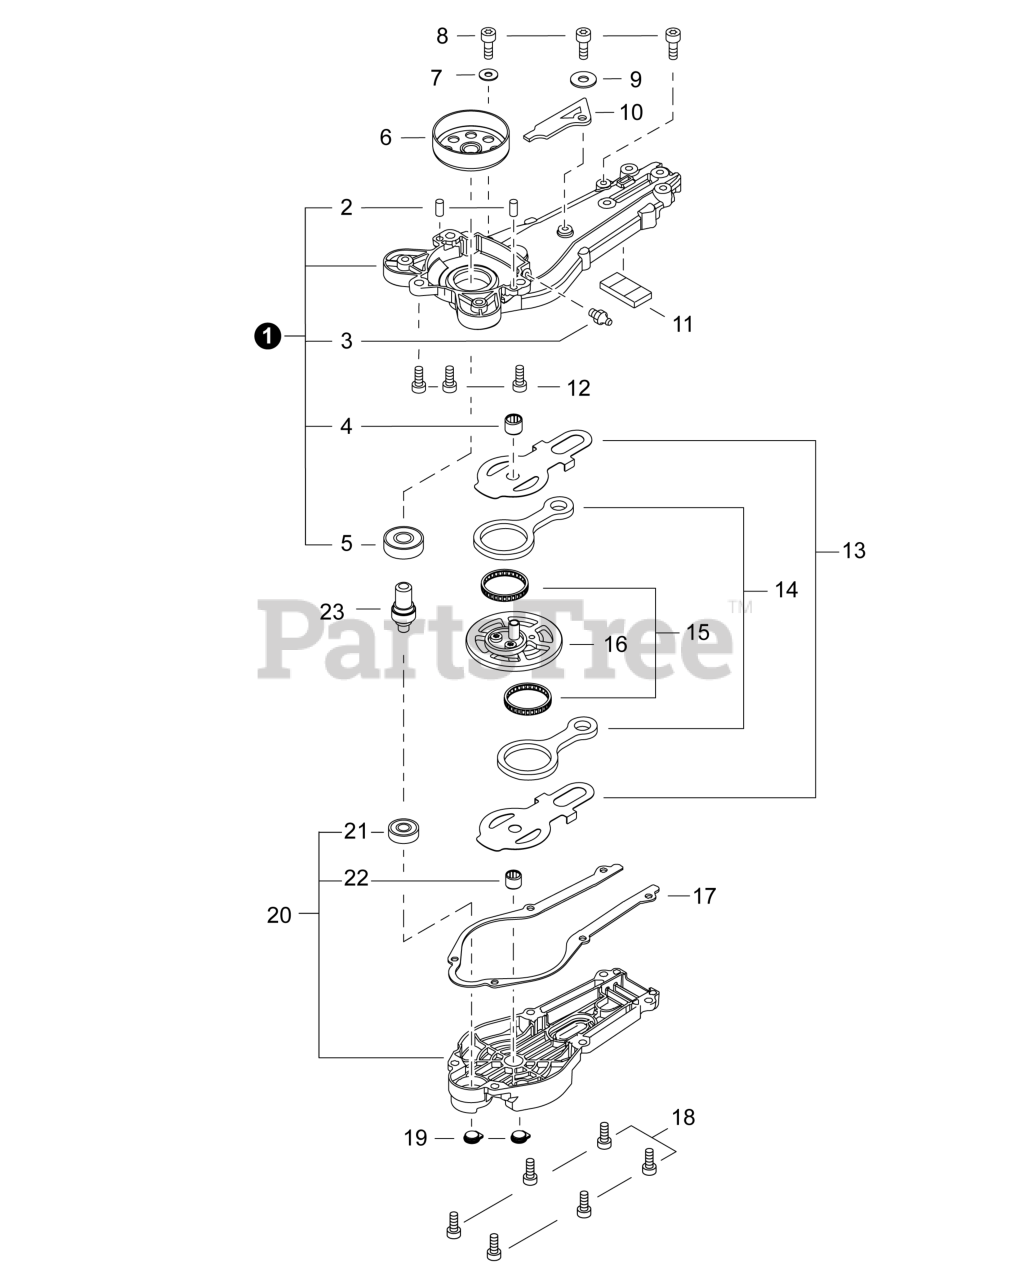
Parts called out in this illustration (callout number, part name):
1	HOUSING ASSY, GEAR CASE
2	PIN, LOCATING 4x8
3	FITTING, GREASE
4	BEARING, NEEDLE 8
5	BEARING, BALL 6001 DDU
6	DRUM, CLUTCH
7	WASHER 5.3x10x1
8	BOLT, TORX 5x6
9	WASHER 5
10	CUSHION
11	PACKING, FELT
12	BOLT, TORX 6x20
13	PLATE, SIDE
15	BEARING, NEEDLE 30
16	GEAR, SPUR
17	GASKET, GEAR CASE
18	BOLT, TORX 5x16
20	COVER ASSY, GEAR CASE
21	BEARING, BALL 608ZZ
22	BEARING, NEEDLE 8
23	SHAFT, PINION
